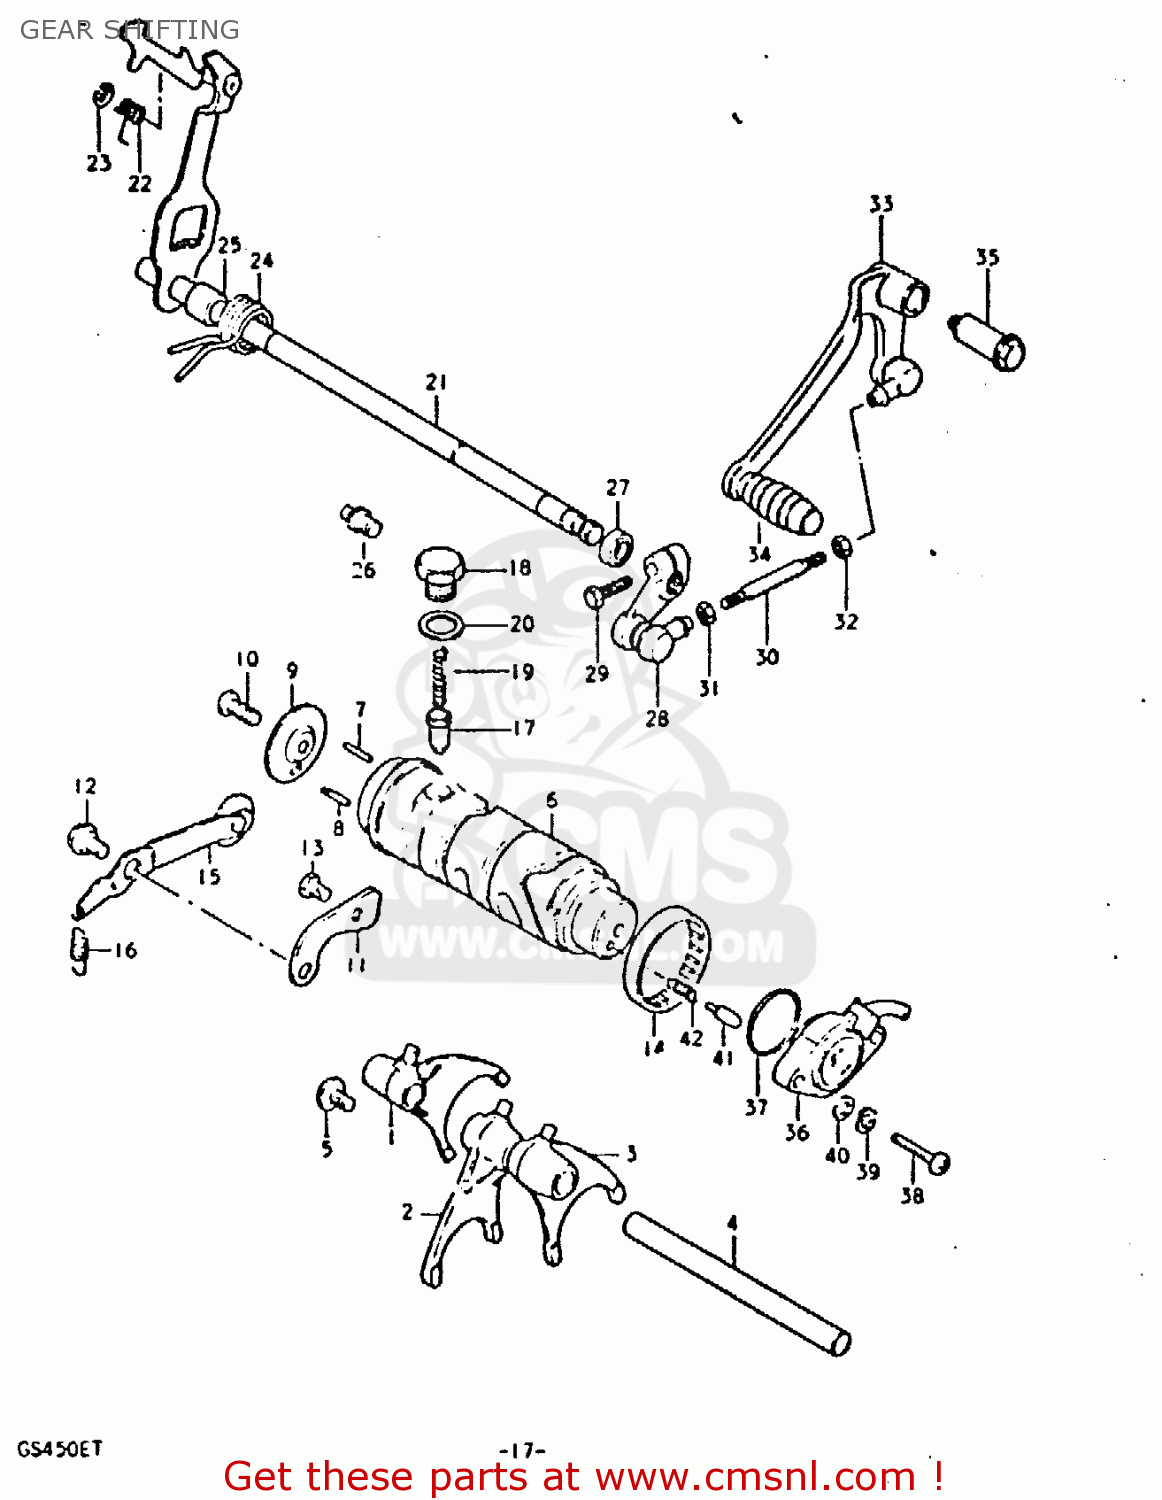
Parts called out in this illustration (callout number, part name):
1	FORK,GEAR SHIFT NO.1
2	FORK,GEAR SHIFT NO.2
3	FORK,GEAR SHIFT NO.2
4	SHAFT,GEAR SHIFT FORK
5	SCREW
6	CAM,GEAR SHIFT
7	PIN(4X18.5)
8	PIN
9	RETAINER,GEAR SHIFT CAM DR PIN
10	SCREW
11	GUIDE,GEAR SHIFTING CABLE
12	BOLT
13	BOLT
14	BEARING(40X47X12)
15	STOPPER,GEAR SHIFT CAM NO.1
16	SPRING
17	STOPPER,GEAR SHIFT CAM NO.2
18	HOLDER,GEAR SHIFT CAM STOP SPR
19	SPRING
20	GASKET(14X19.2X2) (NAS)
21	SHAFT,GEAR SHIFT
22	SPRING
23	E RING
24	SPRING
25	SPACER(12X20X15.3)
26	STOPPER,GEAR SHIFT CAM
27	OIL SEAL
28	ARM,GEAR SHIFT LINK
29	BOLT
30	ROD,GEAR SHIFT LINK
31	NUT
32	NUT
33	LEVER ASSY,GEAR SHIFT
34	RUBBER,GEAR SHIFT PEDAL
35	SHAFT,GEAR SHIFT LEVER
36	BASE ASSEMBLY,NEUTRAL SWITCH TERMINAL
37	O-RING (D:2.4 ID:26.2)
38	SCREW 5X20
39	LOCK WASHER
40	WASHER
41	PIN(5X15.5)
42	SPRING
